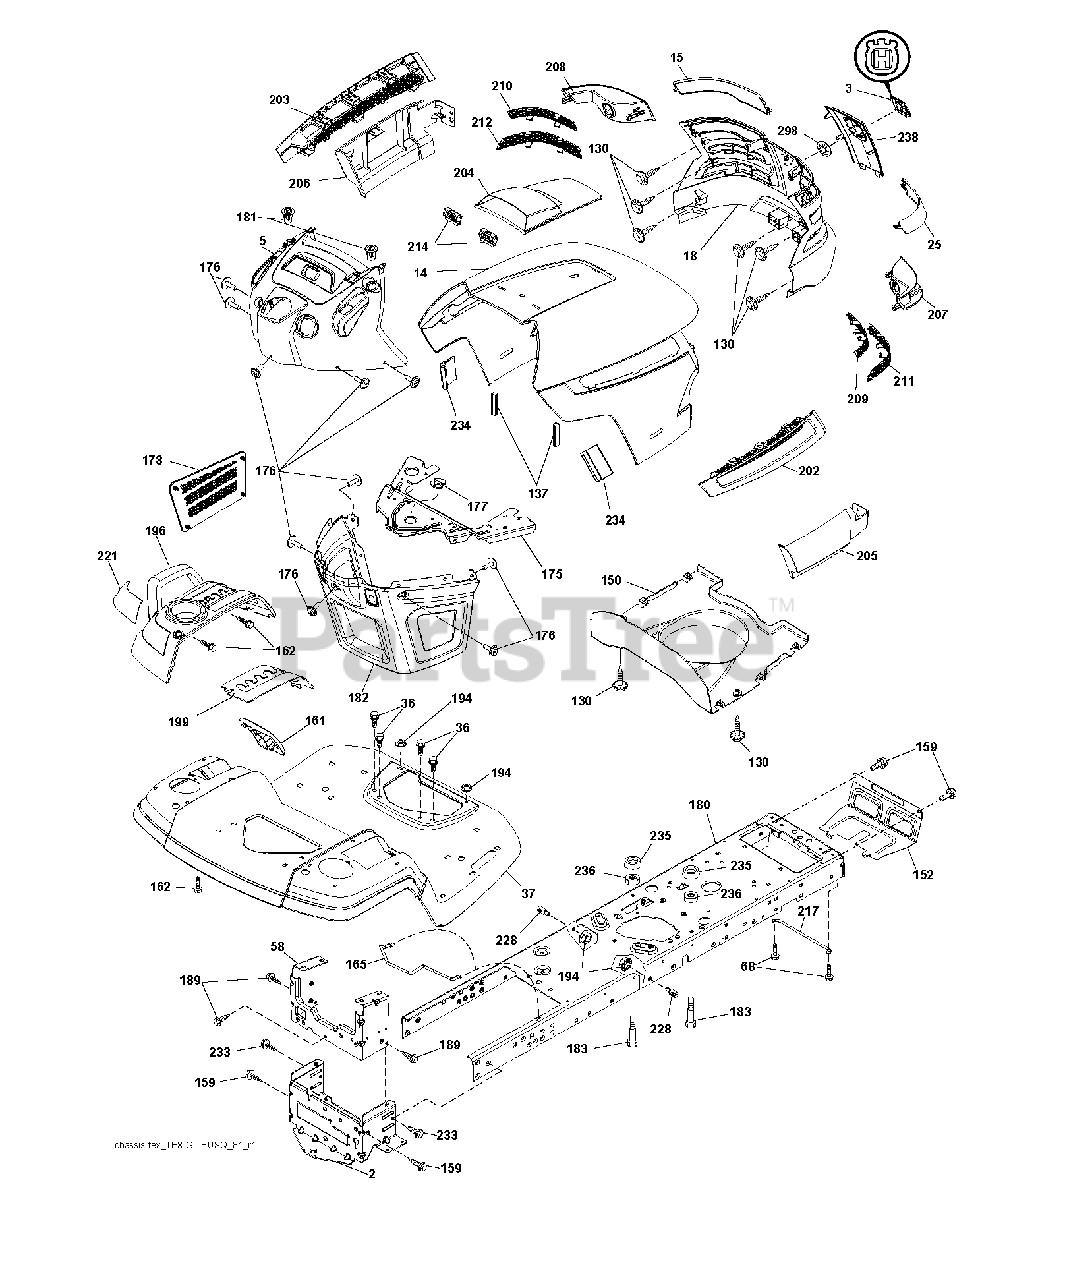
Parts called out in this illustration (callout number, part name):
2	DRAWBAR.LOWER.2PC.18/22
3	RP LOGO
5	DASH.ASM.HUSQ.GT
14	HOOD.ASM.HUSQVARNA.GT.TEX.ORAN
15	LENS.LH.TEX.GT.HUSQ.CL
18	GRILL.ASM.HUSQ.TG/CRD.W/TRIM
25	LENS.RH.TEX.GT.HUSQ.CL
36	SCREW 5/16"
37	FENDER.PNT.TX.GT.CH/FW/DL.HUSQ
58	DRAWBAR.UPPER.2PC,LRG.FENDER
68	SCREW LT
130	SCREW.#10 X 0.750.BOS
137	BUMPER DASH
150	AIR.DUCT.HOOD.TEX.GT.HUSQ
152	SHIELD.BROWNING/DEBRIS
159	SCREW, 3/8-16X3/4
161	CONSOLE.WINDOW.FUEL.HUSQ.GT
162	SCREW.HI-LO.CONSOLE
165	SUPPORT.TANK.REAR.B/TE
175	PLATE.CROSSMEMBER.HUSQ
176	SCREW.#10-24X5/8.RN.QU
177	BUSHING, STEERING
178	CARGO.ASM.NET.TXGT.W/C
180	CHASSIS.STAMPING.LT/GT
181	BUSHING.MNT.FEND.CRGO.
182	DASH.LOWER.COMMON.12V.ADAPTOR
183	BOLT.5/16-18X1-1/4 FULL THD
189	SCREW
194	NUT LOCK HEX FLANGE 5/16-18
196	CONSOLE.ASM.DECKLIFT.HUSQGT.DL
199	PLATE.DECK.LIFT.HUSQVARNA.GT
202	VENT.SIDE.HOOD.RH.HUSQ
203	VENT,SIDE.HOOD.LH.HUSQ
204	HOOD VENT
205	HOOD SIDE SKIRT RH
206	SKIRT.HOOD.SIDE.HUSQ.L
207	BEZEL.RH.TEX.GT.HUSQ
208	BEZEL.LH.TEX.GT.HUSQ
209	INSERT.HEX.GRILL.HUSQ.GREY
210	INSERT.HEX.GRILL.HUSQ.
211	INSERT.HEX.GRILL.HUSQ.
212	INSERT.HEX.GRILL.HUSQ.
214	CLIP.RETAINER.TINNER.
217	ROD.PIVOT.HOOD
221	REFLECTOR.LH.TEX GT HU
228	STUD.FASTNER.W/ANTI-ROTATE
233	BOLT.SHOULDER
234	BUMPER.HOOD.TEX.HUSQVARNA
235	SPACER FENDER
236	NUT.CENTERLOCK.5/16-
238	TRIM.HUSQ.TG/CRD.SERVICE
298	NUT PUSH M
